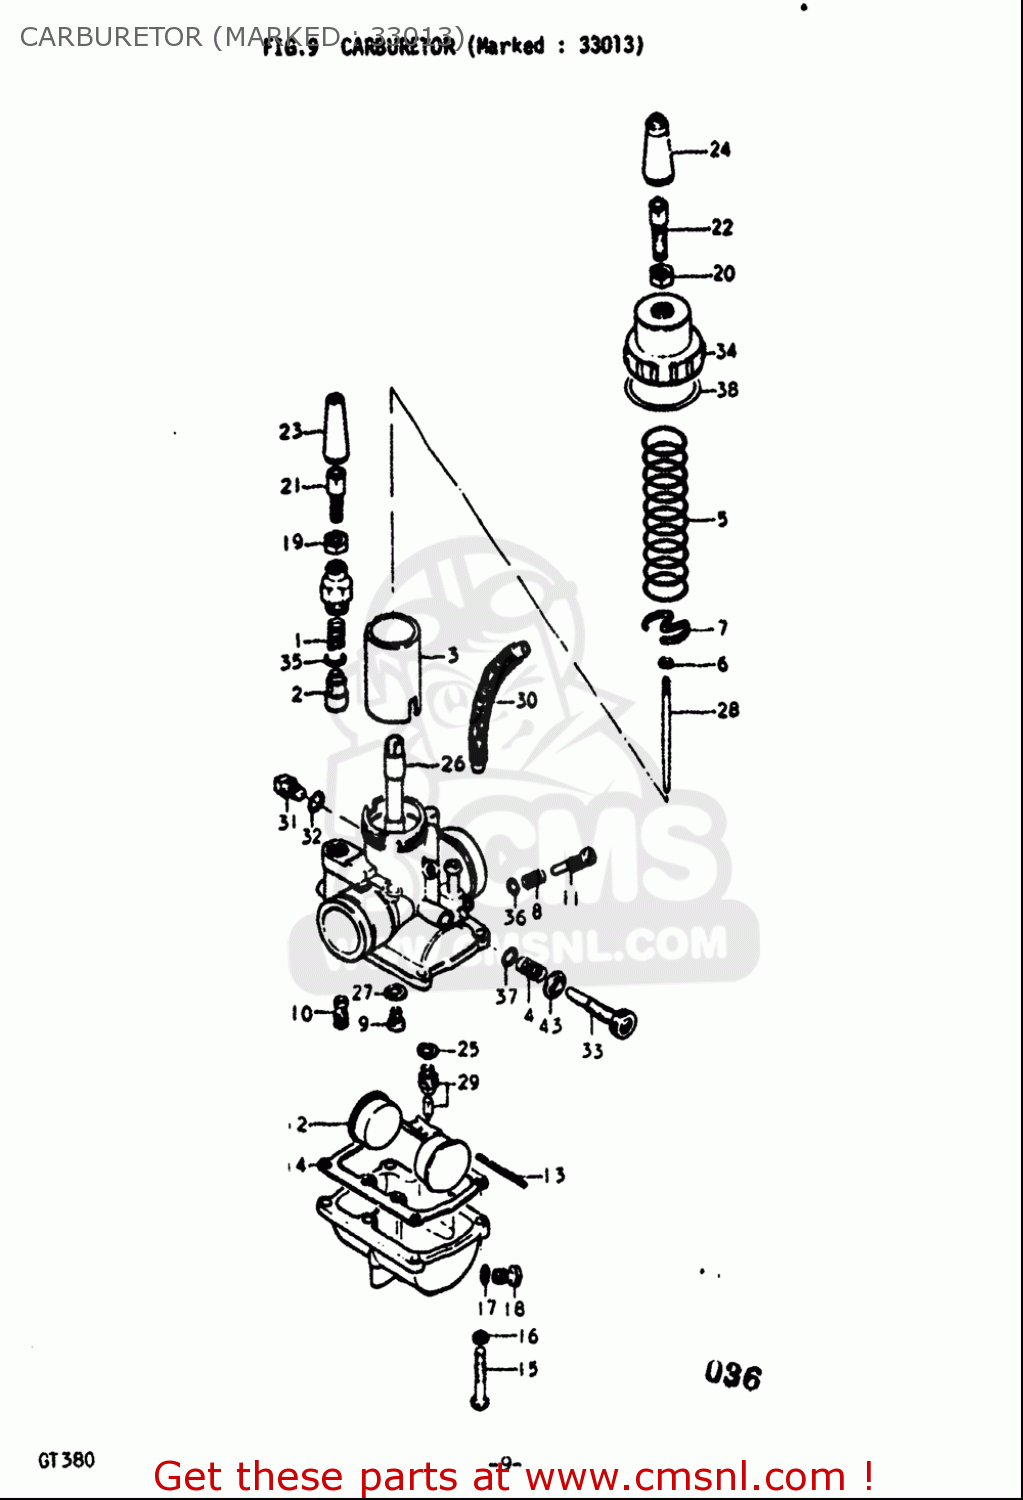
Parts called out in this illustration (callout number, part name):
1	SPRING
2	PLUNGER,STARTER
4	SPRING
6	CLIP
7	SEAT,THROTTLE VALVE SPRING
8	SPRING
9	JET,MAIN
10	JET,PILOT(22.5)
11	SCREW,PILOT AIR ADJUSTING
12	FLOAT
13	PIN,FLOAT
14	GASKET,FLOAT CHAMBER (NAS)
15	SCREW 4X16
16	WASHER,LOCK
17	GASKET,DRAIN,PLUG (NAS)
18	PLUG
19	NUT
21	ADJUSTER,CABLE
23	CAP
25	GASKET,VALVE SEAT (NAS)
27	WASHER
28	NEEDLE,JET
29	VALVE ASSY,NEEDLE
31	BOLT
32	GASKET,THRO VALVE INSPECTION (NAS)
36	O RING
37	O RING
